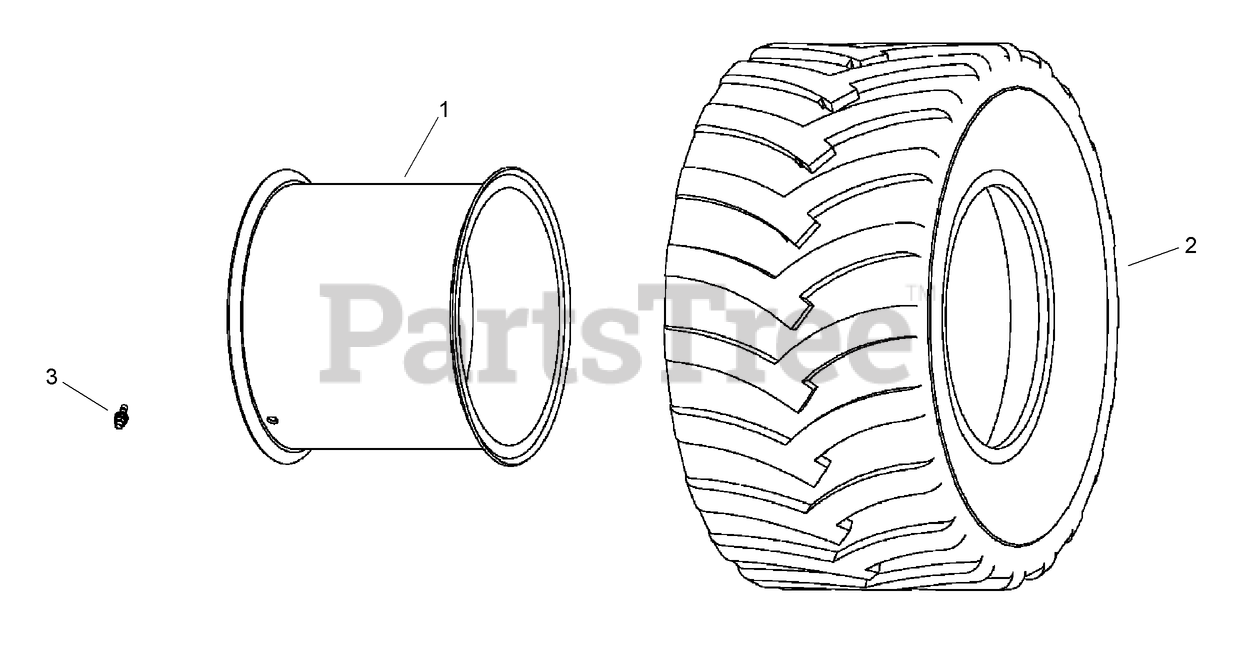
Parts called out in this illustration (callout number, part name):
1	WHEEL-16.1 in for 31 x 15.5-15
2	TIRE-31 x 15.5-15
3	STEM-Valve
